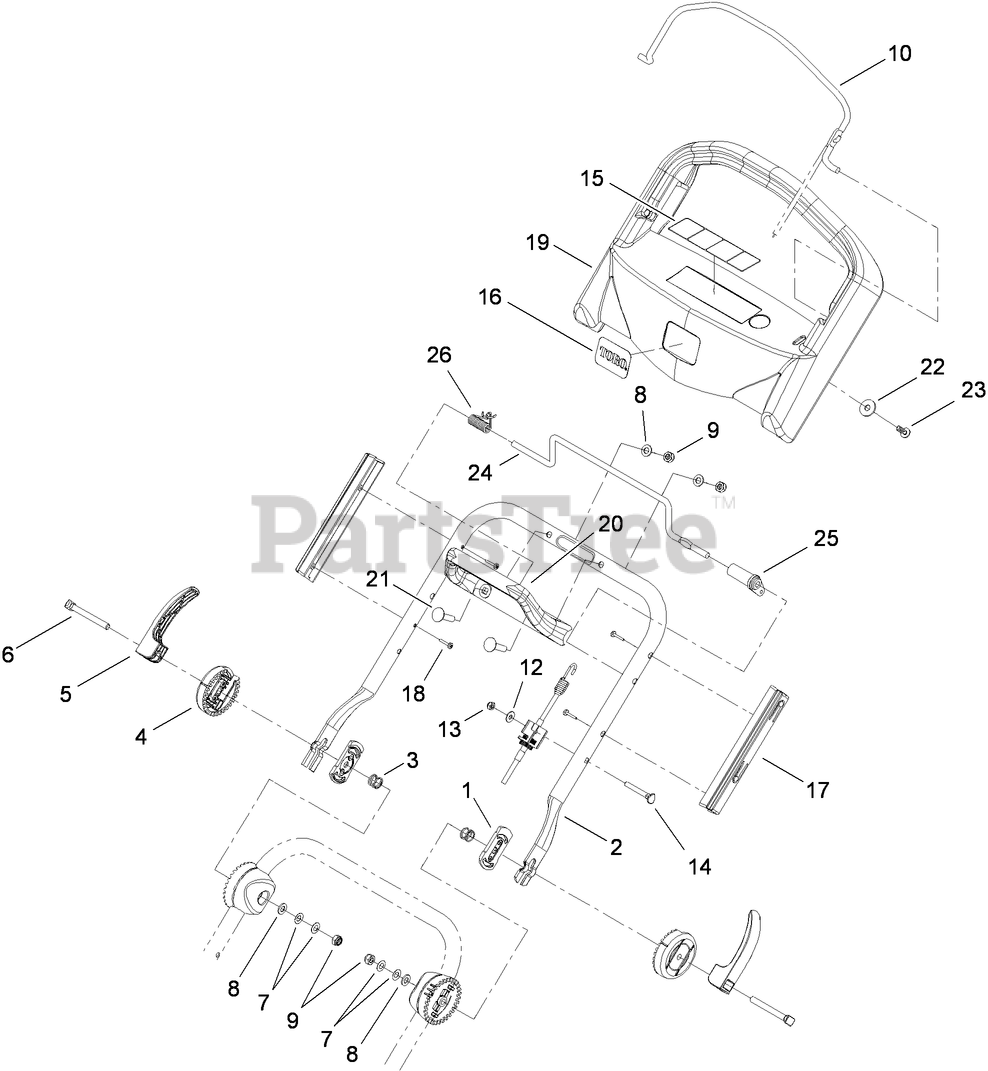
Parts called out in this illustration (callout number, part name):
1	PLATE-ADJUST, HANDLE
3	SPRING-ADJUST, HANDLE
4	MOUNT-HANDLE, UPPER
5	LEVER-LOCKING, HANDLE
6	BOLT-T HEAD, UPPER
7	WASHER-SPRING
8	WASHER-PLAIN
9	NUT-HEX
12	WASHER-FLAT
14	BOLT-CARRIAGE
17	GUIDE-HANDLE, CONTROL
18	SCREW-PPH
19	HANDLE-CONTROL
22	WASHER-PLAIN
25	LEVER-TRACTION
26	Spring-Torsion
